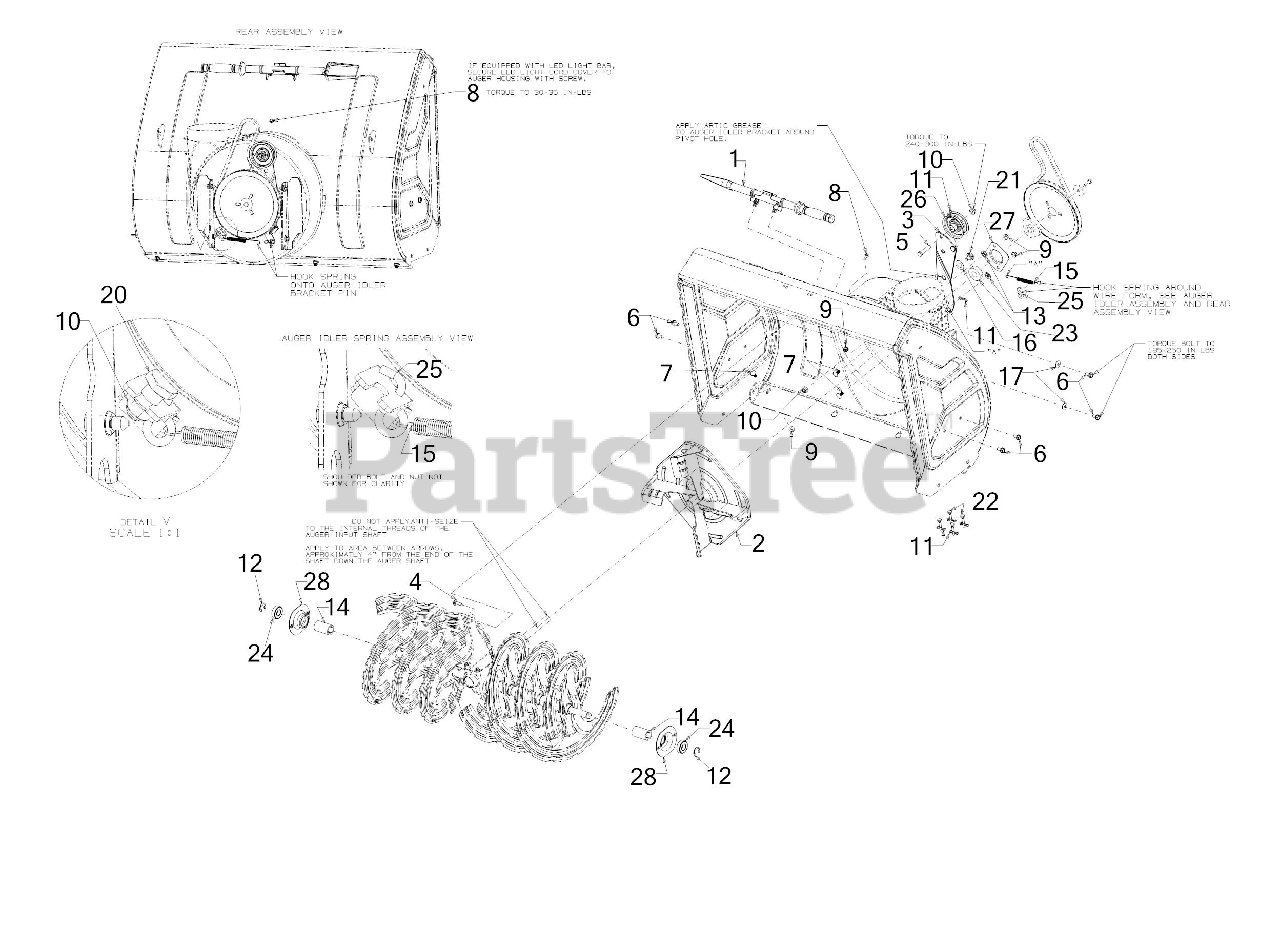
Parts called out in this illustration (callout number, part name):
1	CLEANOUT TOOL
1	CLEANOUT TOOL MOUNTING CLIP
3	AUGER IDLER BRACKET
4	CARRIAGE BOLT 5/16-18 x 1.00
5	HEX SCREW 3/8-16 x 1.75 GR5
6	SCREW 5/16-18 x .750
7	CARRIAGE BOLT 5/16-18 x .75
8	SCREW M6-1 x .625
9	FLANGE LOCK NUT 5/16-18
11	BOW TIE COTTER PIN 1/4-5/16
12	E-RING
13	PUSH ON NUT
14	SPACER 1.25 x .75 x 2.085
15	EXTENSION SPRING .38 OD x 4.59
16	FLAT WASHER
17	BELL WASHER .337 X.867 x .057
20	SHOULDER SCREW .498 DIA x .340
21	SHOULDER SCREW .625
22	SHEAR PIN .25 x 1.50 GR2
23	FLANGE BEARING
24	BALL BEARING
25	ROD SPRING HOOK
26	FLAT IDLER PULLEY 2.75 OD
27	BEARING HOUSIN 1.85 ID
